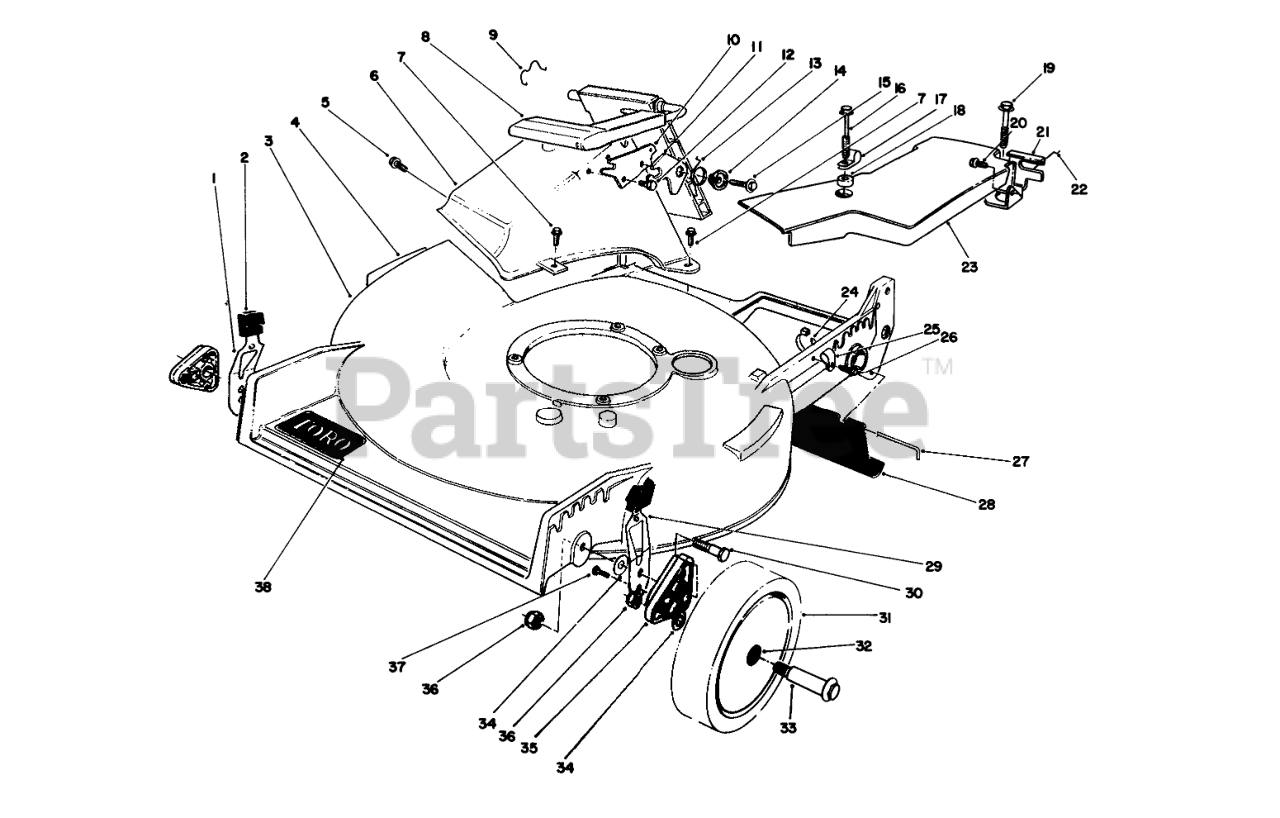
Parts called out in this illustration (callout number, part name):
1	RH SPRING ARM ASSEMBLY
2	KNOB-ARM
3	Housing (Incl. Ref. #4 & 38)
4	DECAL-DANGER
5	SCREW AND WASHER ASM
6	Tunnel-Discharge
7	SCREW-HWH
8	Discharge Door Assembly
9	DOOR RET SPRING
10	DOOR LATCH PLATE
11	SAFETY LATCH
12	SCREW-PLASTITE
13	TORSION SPRING
14	DOOR SPACER
15	SCREW-HWH
16	SCREW-SPECIAL
17	CLAMP-CABLE
18	WASHER
19	SCREW-HHFTF
20	SCREW-HWHTF
21	Bracket-Traction Adj.
22	RETAINER-CABLE
23	Cover-Belt
24	TIE-CABLE
25	CLAMP-CABLE
26	SCREW
27	ROD-SHIELD
28	SHIELD-TRAILING
29	LH SPRING ARM ASSEMBLY
30	SCREW-SHOULDER
31	Wheel & Tire Assembly (Incl. Ref. #32)
32	BUSHING
33	WHEEL BOLT
34	WASHER
35	ARM-PIVOT, FRONT
36	Nut
37	SCREW-HWH
38	DECAL
